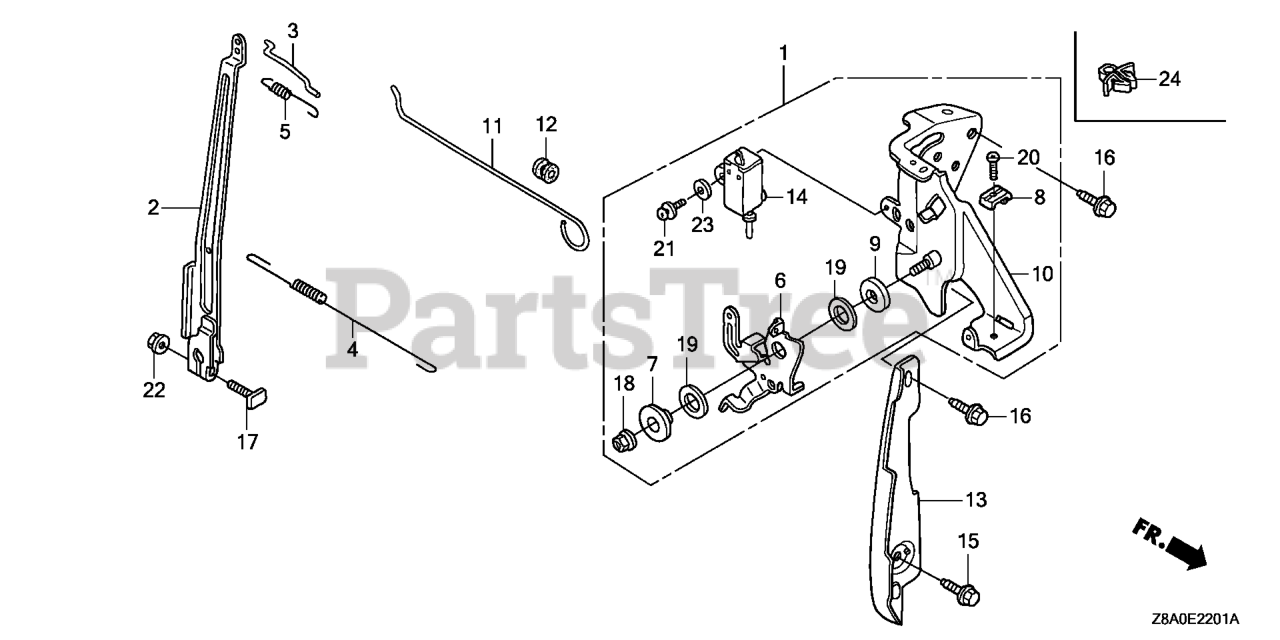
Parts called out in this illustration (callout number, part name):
1	CONTROL ASSY.
2	ARM, GOVERNOR
3	ROD, GOVERNOR
4	SPRING, GOVERNOR
5	SPRING, THROTTLE RETURN
6	LEVER, CONTROL
7	WASHER, CONTROL LEVER
8	HOLDER, CABLE
9	SPACER, CONTROL LEVER
10	BASE, CONTROL
11	ROD, CHOKE CONTROL
12	GROMMET, CHOKE ROD
13	PLATE, SIDE
14	SWITCH ASSY., ENGINE STOP (N.O)
15	BOLT, FLANGE (6X12) (CT200)
16	BOLT, FLANGE (6X14)
17	BOLT, GOVERNOR ARM
18	NUT, SELF-LOCK (6MM)
19	WASHER (12.5MM)
20	SCREW, PAN (5X16)
21	SCREW-WASHER (4X12)
22	NUT, FLANGE (6MM)
23	WASHER, PLAIN (4MM)
24	CLIP, CABLE (A)
